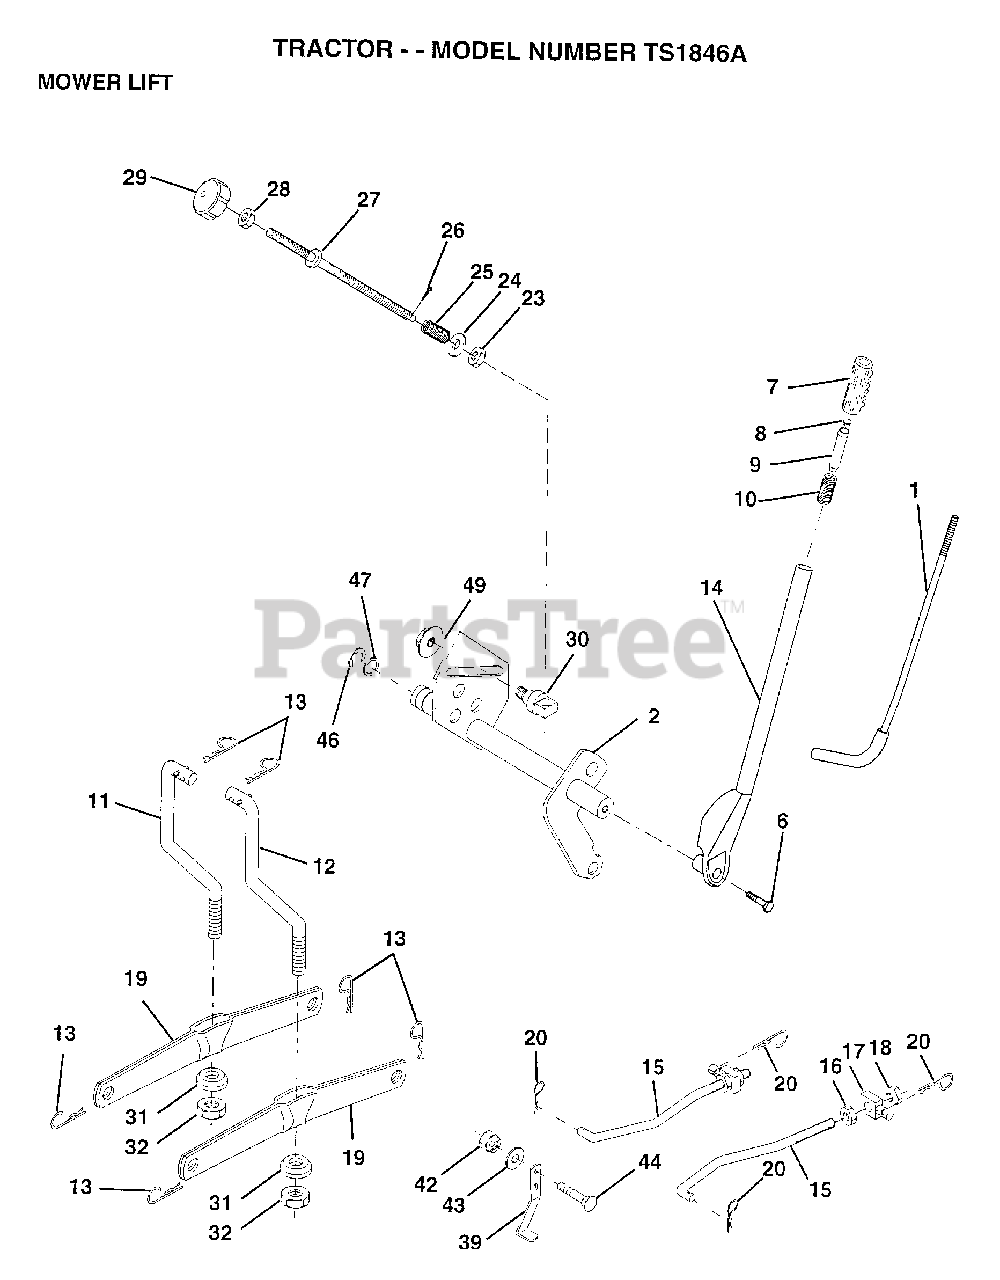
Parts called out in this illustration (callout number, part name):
1	LEVER ROD LT
2	SHAFT LIFT W/IND
6	"BOLT,HEX"
7	GRIP HANDLE
10	SPRING T
11	LINK.LIFT.LH.GTV
12	LINK.LIFT.RH.GTV.
15	LINK.FRONT
16	NUT
17	TRUNION
18	NUT.LK.W/WSH.1/2.
19	ARM SUSP REAR
20	RETAINER.SPRING
23	NUT T
24	WASHER
25	SPRING.COMP.INF.H
27	ROD.ADJ.LIFT
28	NUT
29	KNOB INF 3/8-16
30	TRUNNION
31	BEARING PVT LH
32	NUT.CROWNLOCK.3/8
39	STOP.OVER.CENTER
43	WASHER GT
44	BOLT
46	E-RING
47	WASHER
49	NUT.HXFLG.LOCK.
